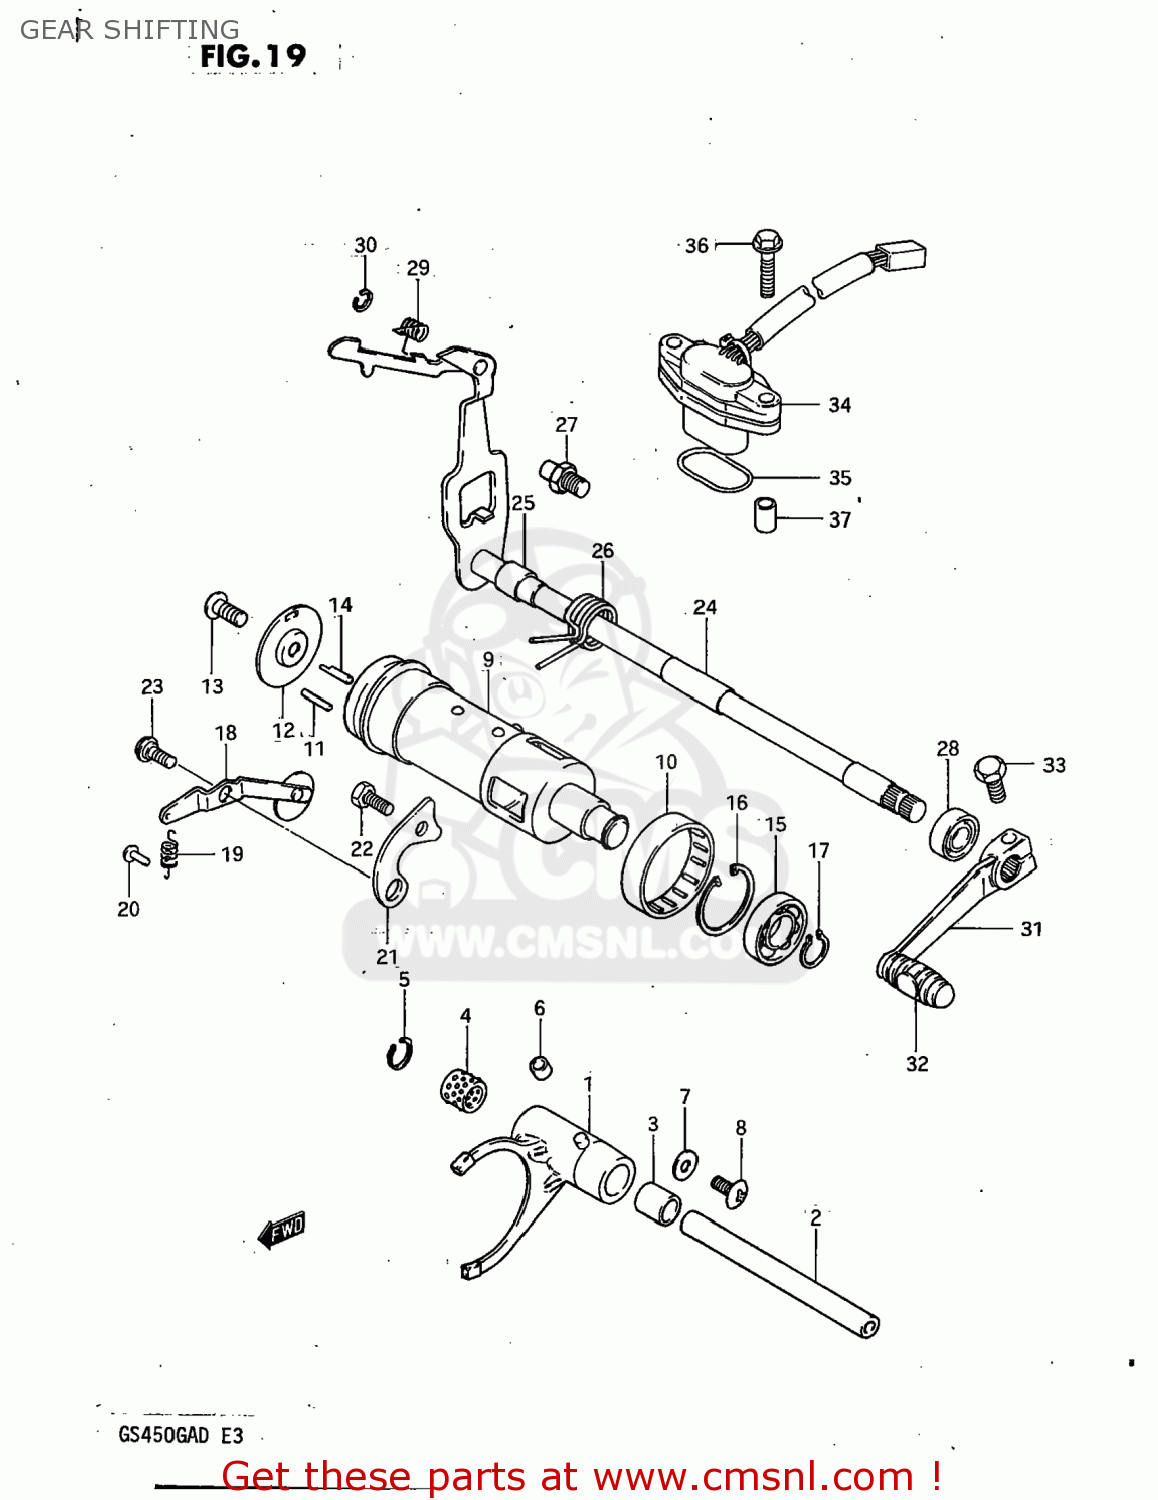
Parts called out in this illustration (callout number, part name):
1	FORK,GEAR SHIFT
2	SHAFT,GEAR SHIFT FORK
3	SPACER (10X14X17)
4	BEARING
5	CIRCLIP
6	SPACER
7	WASHER
8	SCREW
9	CAM,GEAR SHIFT
10	BEARING(40X47X12)
11	PIN(4X18.5)
12	RETAINER,GEAR SHIFT CAM DR PIN
13	SCREW
14	PIN
15	BALL BEARING
16	CIRCLIP
17	CIRCLIP,15MM
18	STOPPER,GEAR SHIFT CAM NO.1
19	SPRING
20	RIVET
21	GUIDE,GEAR SHIFTING CABLE
22	BOLT, UPPER
23	BOLT
24	SHAFT,GEAR SHIFT
25	SPACER(12X20X15.3)
26	SPRING
27	STOPPER,GEAR SHIFT CAM
28	OIL SEAL
29	SPRING
30	E RING
31	LEVER ASSEMBLY,GEAR SHIFTING
32	RUBBER,GEAR SHIFT PEDAL
33	BOLT
34	BASE ASSEMBLY,NEUTRAL SWITCH TERMINAL
36	BOLT
37	PIN(6.2X8X11)
